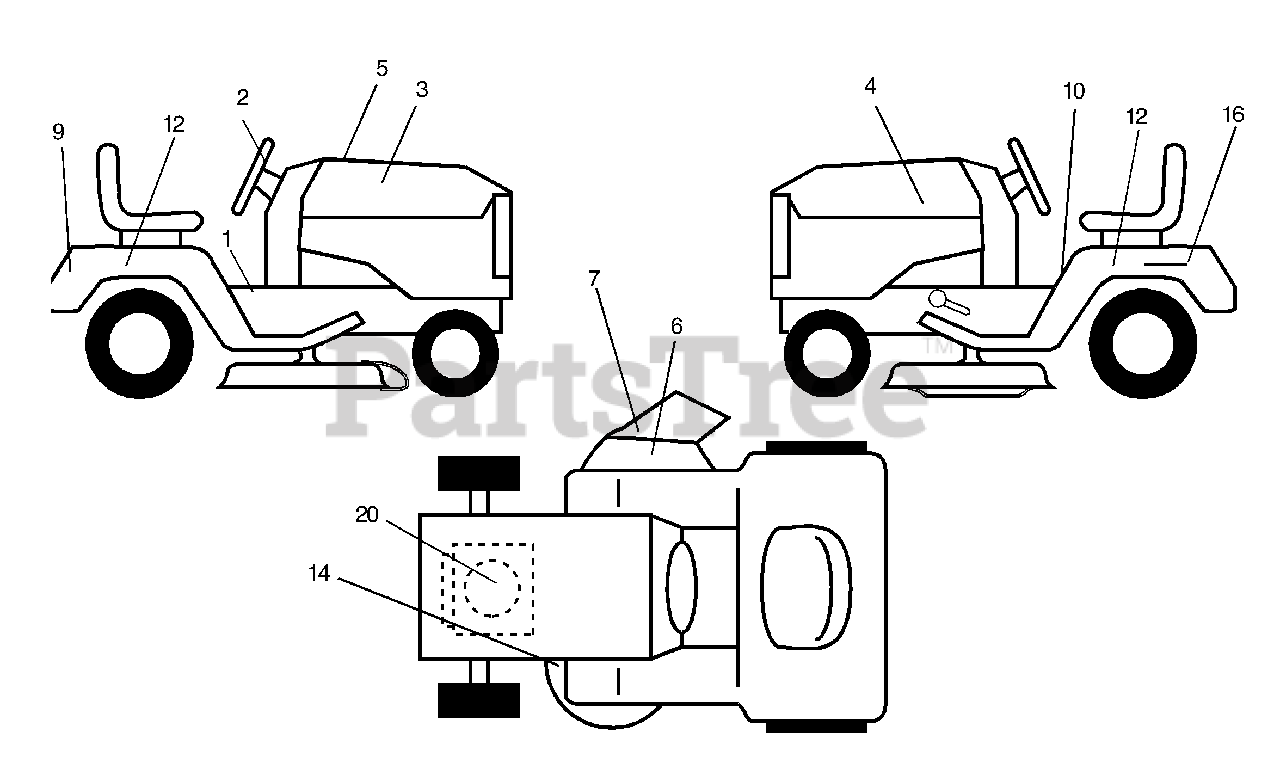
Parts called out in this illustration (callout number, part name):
1	Decal Instruction Operat English/French
2	Decal Ins Strg Wh
3	Decal Hood Rh
4	Decal Hood Lh
5	Decal Final Replacement
6	Decal, Warning
7	Decal Deck "B" 42"
9	Decal Fender Logo
10	Decal Danger English
12	Decal Fender
14	Decal V-belt Schematic 42"
16	Decal Battery Danger/Poison
20	Decal HP Engine
20	Decal Lift Handle
20	Decal By-Pass
